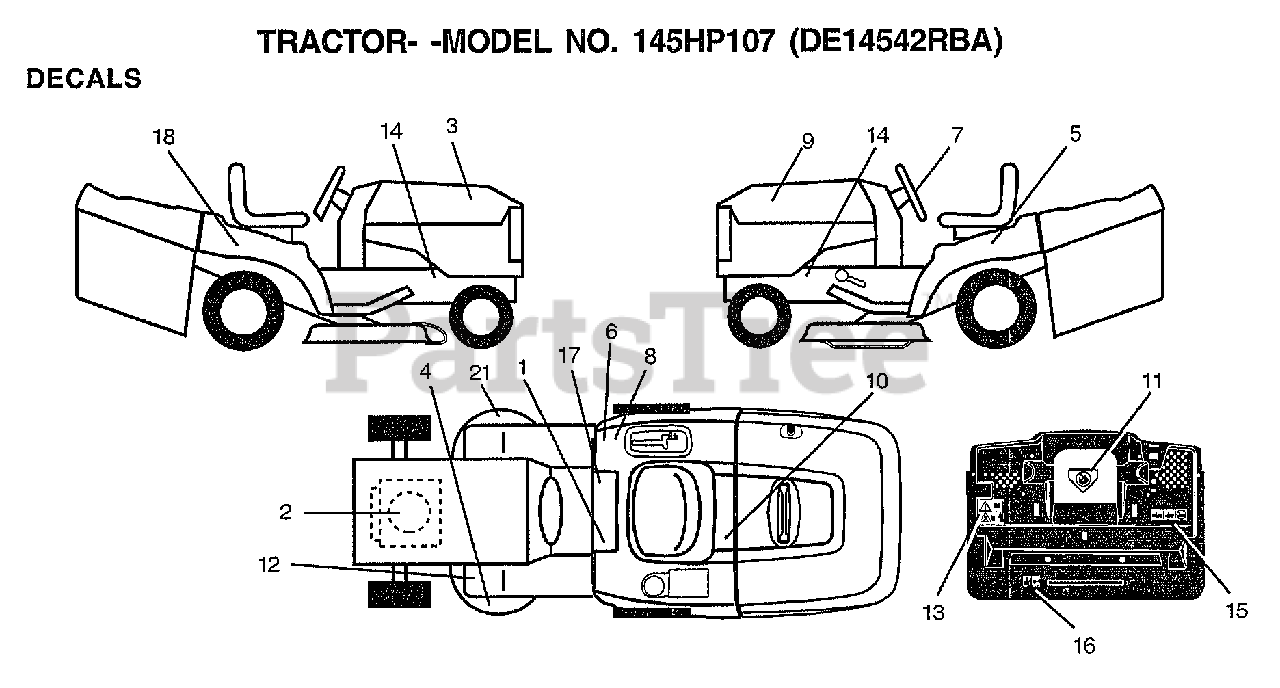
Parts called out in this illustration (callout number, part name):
1	DECAL.READ.O.MANU
2	DECAL, ENGINE
3	DECAL, HOOD
4	DECAL.DECK.MOWER
5	DECAL FENDER
7	DECAL.INST.STEERING
8	DECAL.EURO.ST.CE.
9	DECAL, HOOD
10	DECAL.BATRY.3-3908
11	DECAL.DANGER.CUTF
12	DECAL-BRAKE/CLUTC
13	DECAL.WARNING.BACKPLATE.CRD
14	"DECAL CHASSIS,HOT"
15	DECAL, OPER BAG
16	DECAL.DRAWBAR.LDL
17	DECAL BRAK PARK
18	DECAL FENDER
21	DECAL.DECK.HEX.BELT
